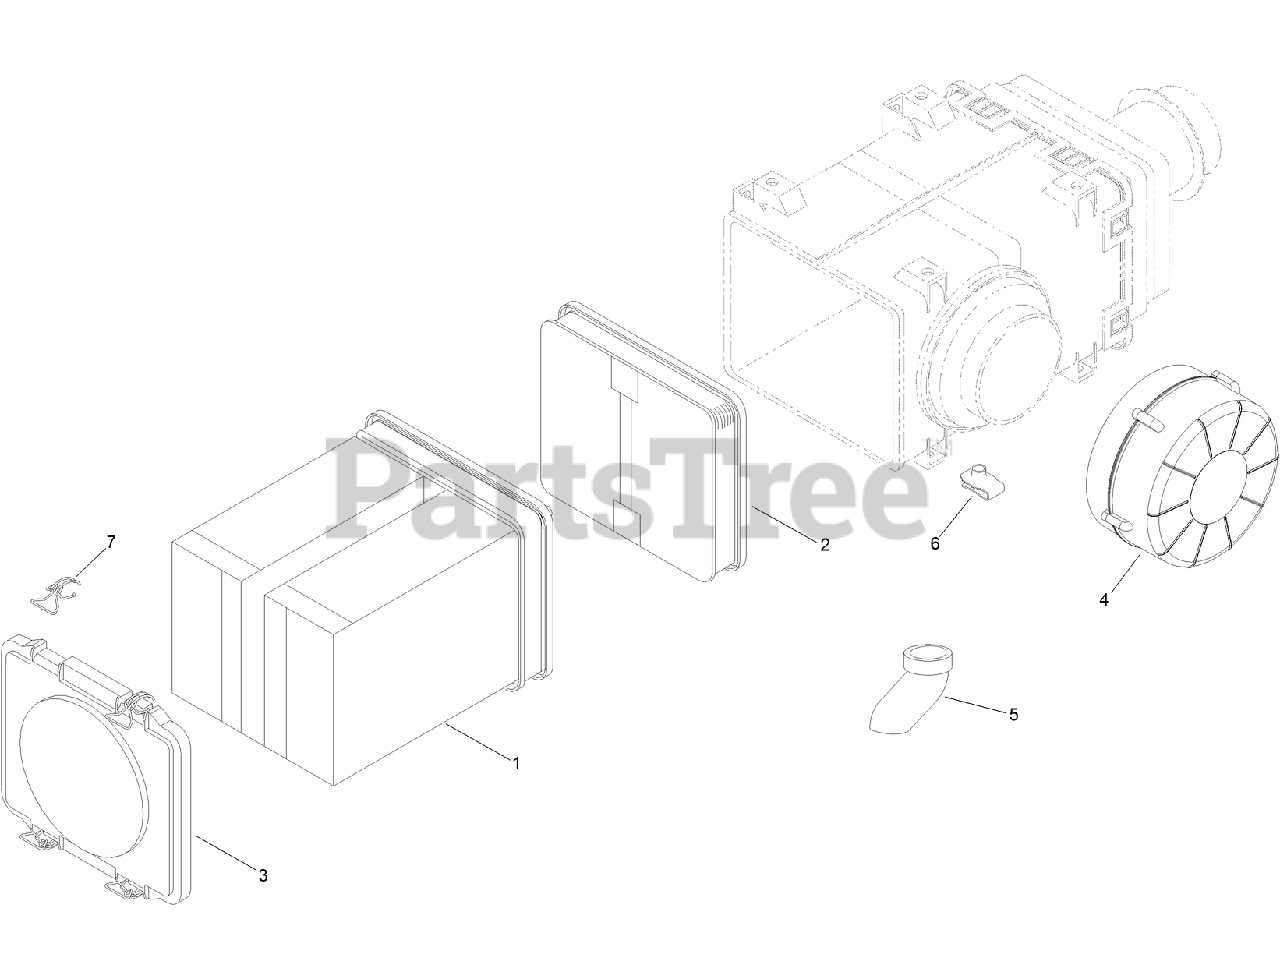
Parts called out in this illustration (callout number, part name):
1	CLEANER-AIR, PRIMARY
2	CLEANER-AIR, SAFETY
3	COVER-SERVICE, FRONT
4	CLEANER-PRE
5	VALVE-EJECTION, DUST
6	CLIP-MOUNTING, M6
7	LATCH-COVER, SERVICE
